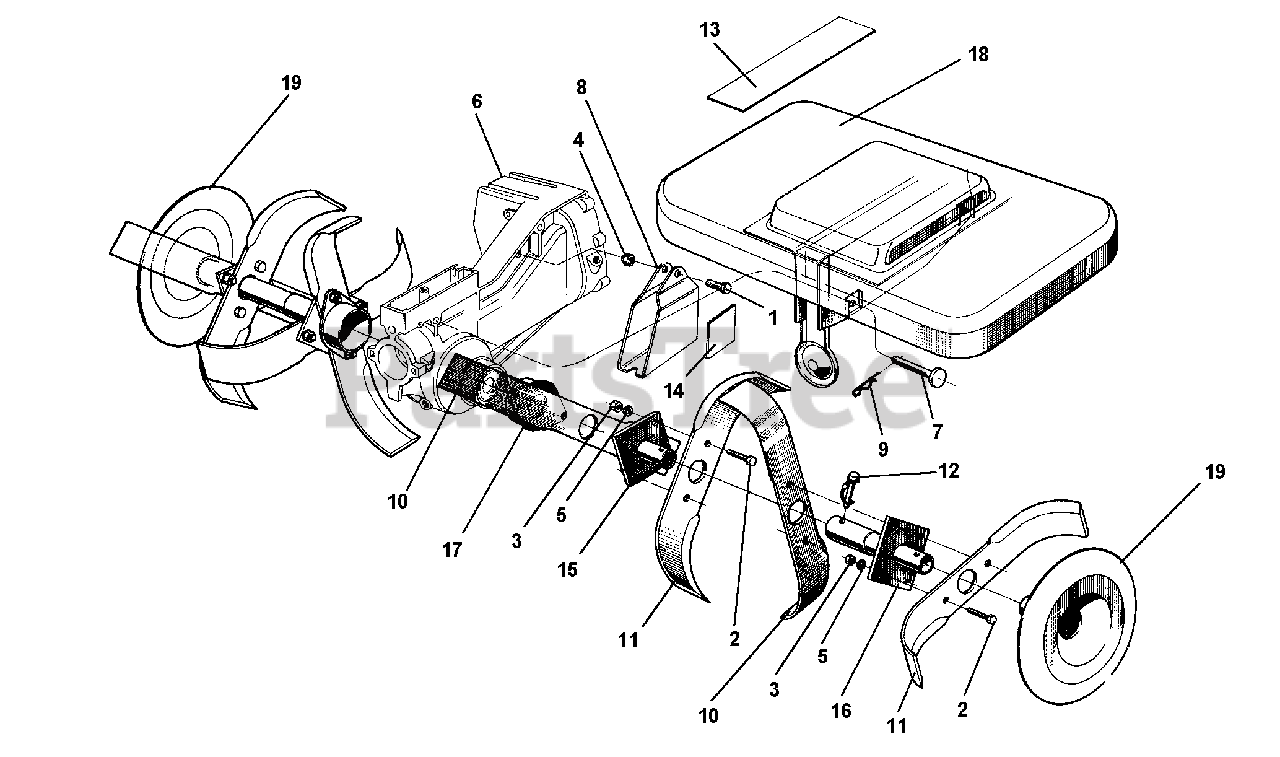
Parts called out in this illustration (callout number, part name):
1	SCREW M6 X 28
2	SCREW TE M8 X 20 UNI 5739 5S
4	NUT, SELF LOCKING M6
5	WASHER, LOCK 8.4
8	GEARBOX PROTECTION
10	RIGHT KNIVE
13	ROTARY HOE HOOD TRANSFER
14	TRANSFER FOR PROTECTION
19	PROTECTION DISC
